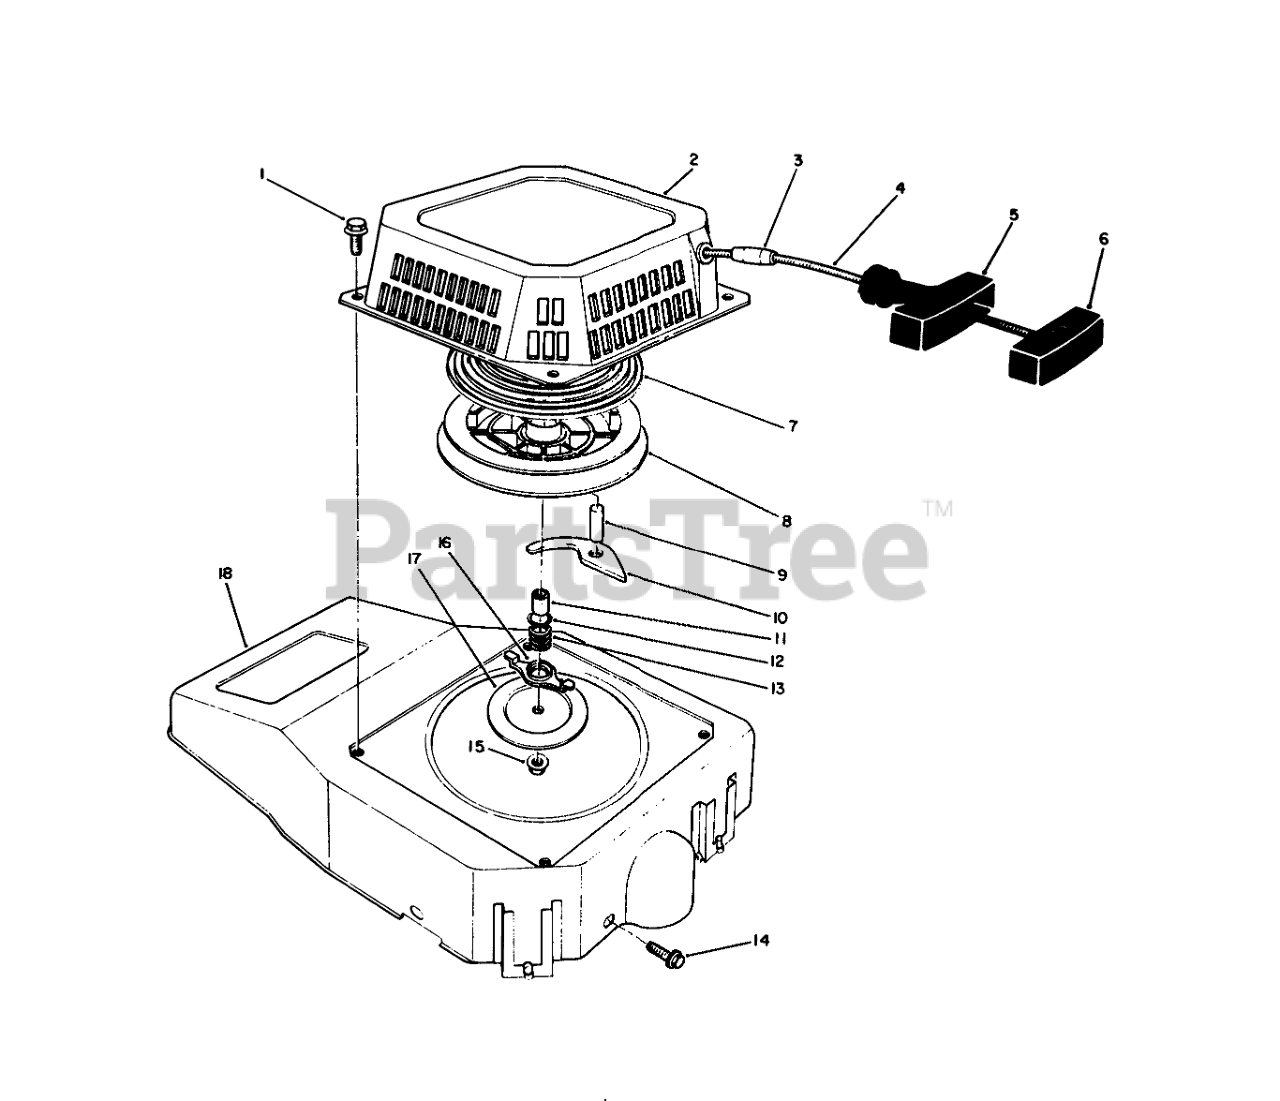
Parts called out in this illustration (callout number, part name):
1	SCREW-HHF
2	Case-Recoil
4	ROPE-STARTER
5	HANDLE
6	RETAINER HANDLE
7	SPRING
11	Spacer
12	WASHER
13	Spring-Friction
16	Guide-Paw
17	PLATE
18	SHROUD
